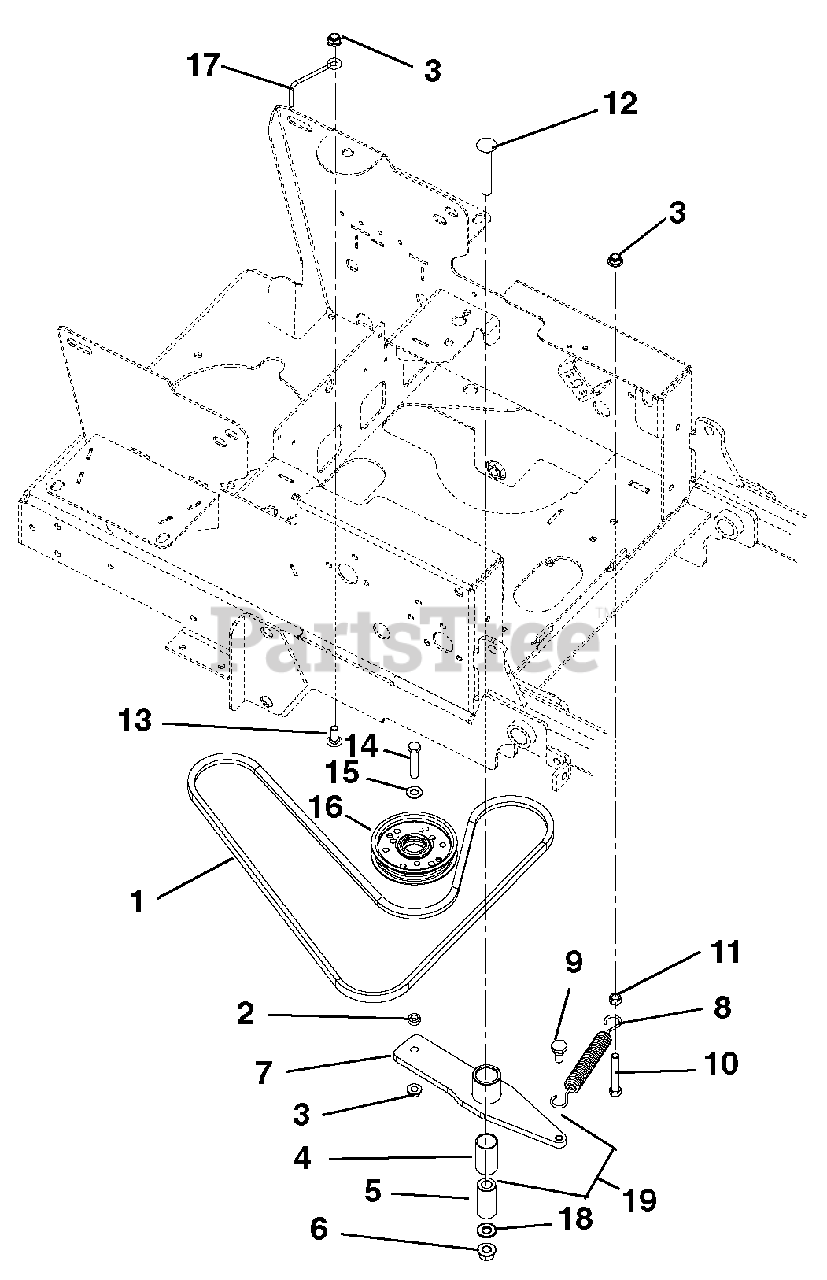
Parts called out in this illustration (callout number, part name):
1	V-BELT, 4L-WRAPPED
2	BSHG-SLV .377X.624X.235
3	@NUT-LK-NYL-FLG .38-16 YWZC
4	BSHG, 1.00 X 1.125 X 1.937
5	BSHG, SPCR .502X.997X2.03 PM
6	@NUT-LK-NYL-FLG .50-13 YWZC
7	WMT-HYDRO DRIVE IDLER ARM
8	SPRING, EXTENSION
9	BLT,SHLDR EP .38-16X.30 HEX YZ
10	@BLT-HEX .38-16X2.50 GR5 YWZC
11	@NUT-HEX .38-16 YWZC
12	@BLT-HEX .50-13X3.25 GR5 YWZC
13	@BLT-RDHDSQNK .38-16X1.00 G5YZ
14	@BLT-HEX .38-16X2.00 GR5 YWZC
15	@WSHR-FL-STL.406X.812X.065 YWZ
16	IDLER-FLAT 4.00 X .38 NWHAMSHR
17	BELT FINGER
18	WSHR-FL-STL.511X1.441X.125 YWZ
19	ASM, IDLER PIVOT ARM (HYDRO)
